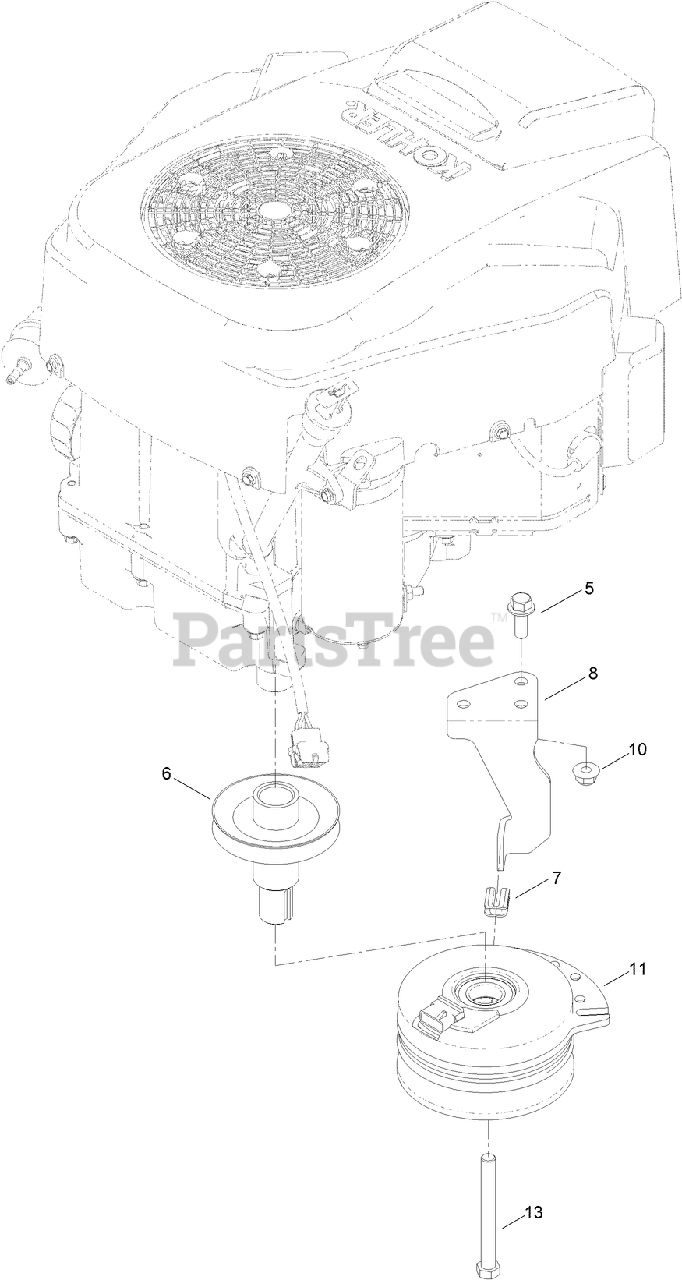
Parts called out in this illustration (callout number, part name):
5	SCREW-HHF
6	PULLEY-ENGINE
7	ISOLATOR-CLUTCH
8	STOP-CLUTCH (NARROW)
10	NUT-HF, NI
11	CLUTCH-ELECTRIC
13	SCREW-HH
